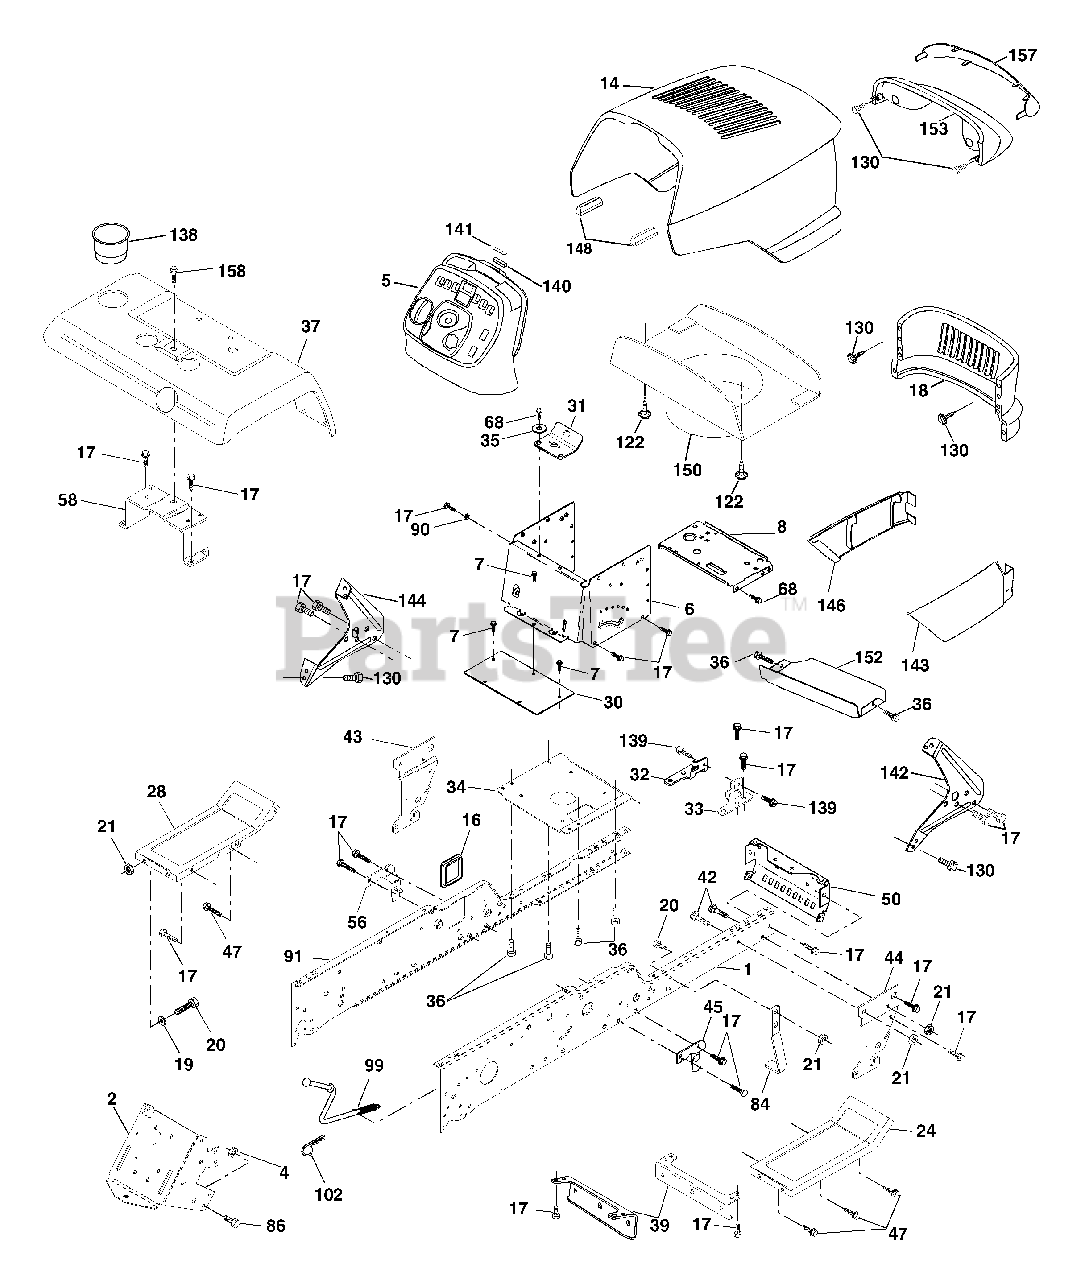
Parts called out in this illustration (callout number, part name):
1	Rail, Frame RH
2	Drawbar,Gt
4	Nut, Crownlock 7/16-14Unc
5	Dash
6	Dash Asm., Lower
7	Screw, Thd Cut 1/4-20 x 1/2
8	Support, Battery
14	Hood Asm., Pnt
16	Cover, Access
17	Screw, 3/8-16 x 3/4
18	Grille
19	Washer 13/32 x 13/16 x 12 Ga.
20	Bolt, Fin Hex 3/8-16 x 1
21	Nut, Crownlock 3/8-16 Unc
24	Footrest, RH
28	Footrest, LH
30	Saddle, Hydro 1995
31	Bracket, Supt 1-pc VGT Steering
32	Bracket, Pivot Chassis LH
33	Bracket, Pivot Chassis RH
34	Plate Asm. Engine Chassis
35	Washer 11/32 x 11/16 x 16 Ga.
36	Screw 5/16-18 x 3/4
39	Bracket, Axle Front
42	Bolt, Carriage 3/8-16 x 1
43	Bracket, Spnsn Front Lh
44	Bracket, Spnsn Front Rh
45	Bracket Asm., Susp Chassis Rh
47	Screw Thdrol 3/8-16 x 1/2 TYT
50	Bracket, Chassis Front
56	Bracket Asm., Susp Chassis Lh
58	Bracket Asm., Fender
68	Screw, Thd 5/16-18 x 1/2
84	Stop, Over Center Mower
86	Bolt, Fin Hex 7/16-14 Unc x 1
90	Washer, Lock External Tooth 3/8
91	Rail, Frame Lh
99	Rod By Pass
102	Retainer,Spring
122	Screw Hex Wshd 8-18 x 7/8
130	Screw HWHD Hi-Lo #13-16 x 3/4
138	Cupholder YTGT
139	Bolt Shoulder 5/16-18 TT
140	Magnet YTGT
141	Stricker Plate YTGT
142	Bracket Dash RH
143	Skirt Grill RH
144	Bracket Dash LH
146	Skirt Grill LH
148	Extrusion Bumper
150	Duct Heat Hood
152	Shield Browning
153	Lens, Asm Headlight bar
157	Lens, Bar
158	Screw Thdrol. 3/8-16 x 1/2
